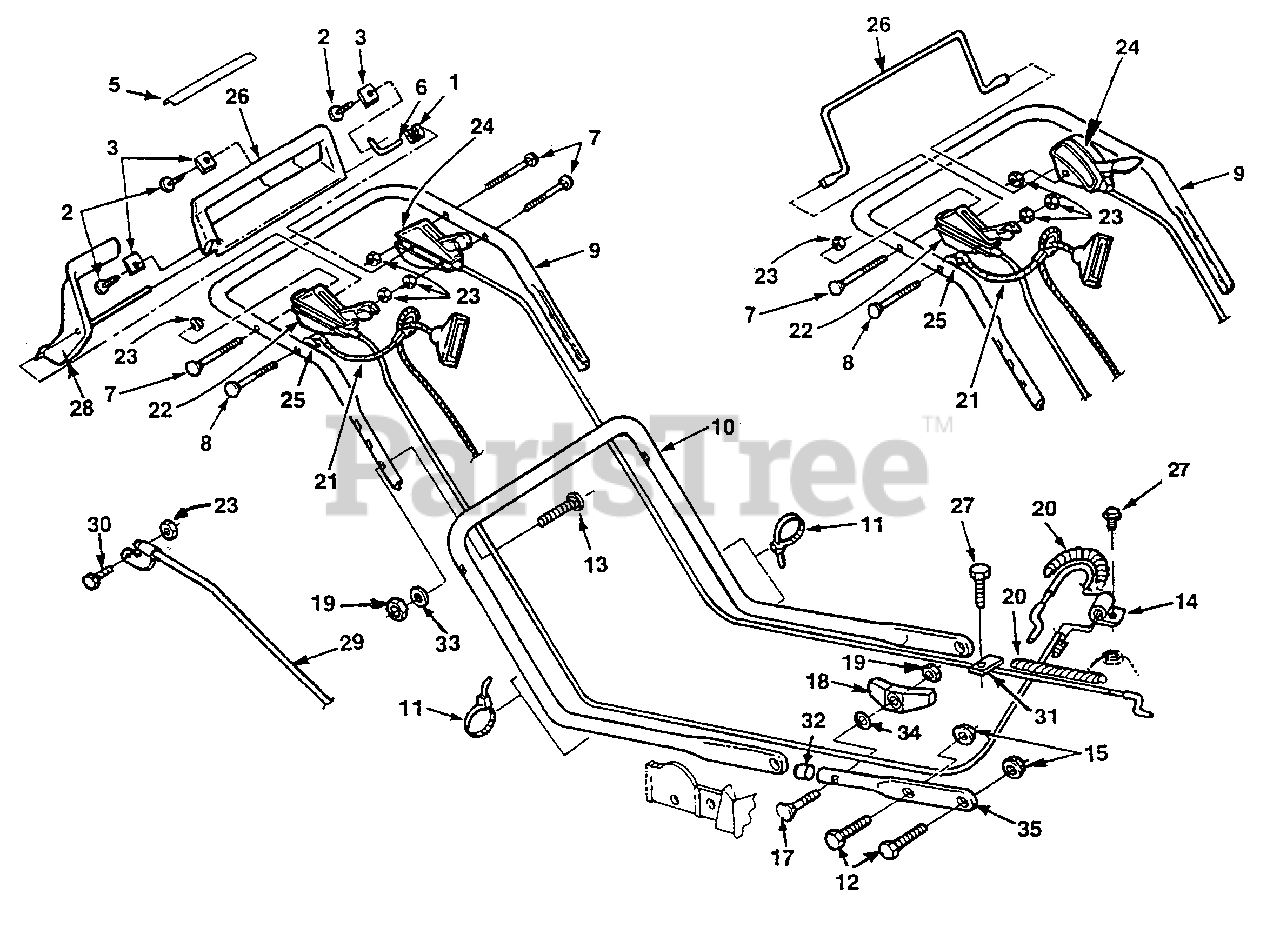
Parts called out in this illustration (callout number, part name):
1	SPRING - Compression
2	SCREW 1/4-10 x 5/8" Truss Tap
3	CLAMP - Pivot Shaft
5	DECAL - Starting Instr.
6	PIVOT SHAFT
7	BOLT - 1/4-20 x 2" Carriage
8	BOLT - 1/4-20 x 2-1/4" Carriage
9	HANDLE - Upper
10	HANDLE - Lower
11	CABLE TIE
12	BOLT - 5/16-18 x 1" HHCS
13	BOLT - 5/16-18 x 1-1/2" CARR. GR5
14	CLAMP - Engine Control Cable
15	NUT - 5/16-18 Flange Lock
17	BOLT - Handle Joining
18	WINGKNOB - Handle
19	NUT - 5/16-18 Hex
20	COVER - Cable
21	GRIP RESTRAINT
22	CABLE - Engine/Blade Control
23	NUT - 1/4-20 Lock
24	CONTROL - Throttle w/Cable
25	WASHER - 5/16 Curved
26	BAIL - Engine/Blade Control
27	SCREW - 1/4-20 x 5/8" Hex Tap
28	TRACTION LEVER
29	CABLE - Drive Control
30	SCREW - 1/4-20 x 1-1/2" HHCS
31	CLAMP - Cable
32	PLUG - Cap
33	WASHER - 5/16" Lock
